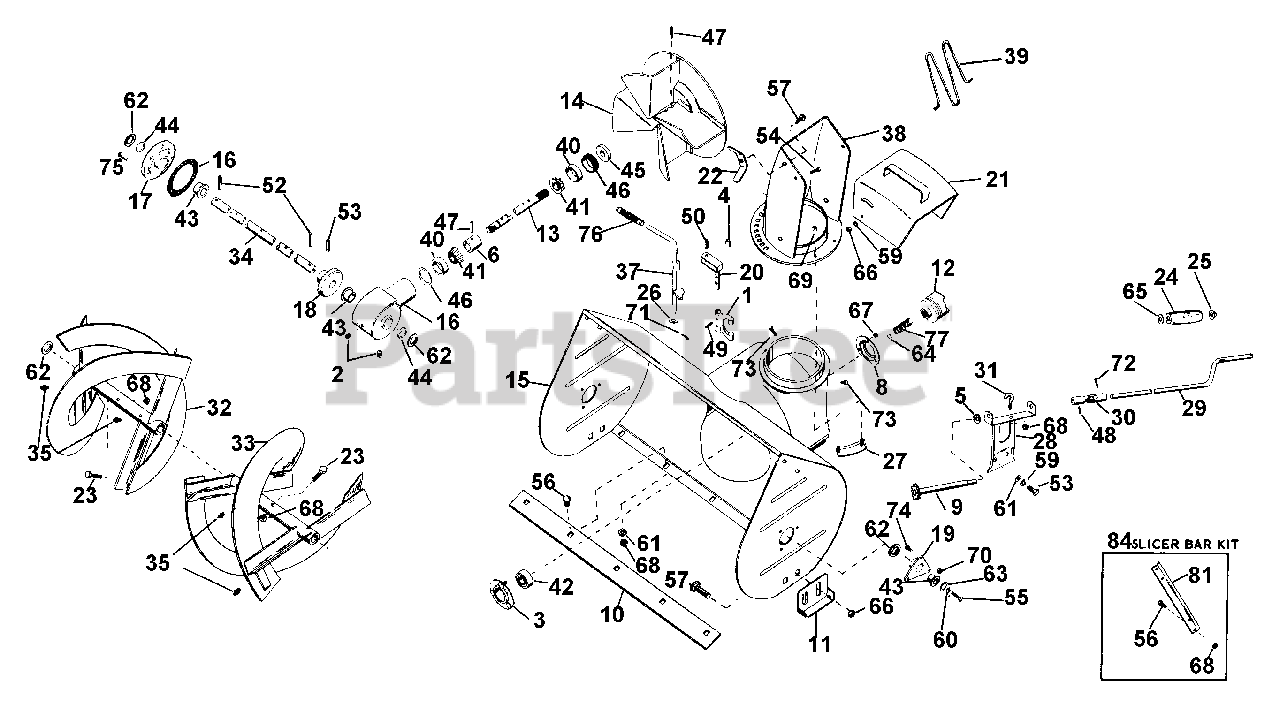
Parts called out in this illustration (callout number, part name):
1	CLUTCH FORK
2	PIPE PLUG
3	BEARING FLANGE
5	WAVE WASHER .531X.781X.125FH
6	BEARING SPACER
8	BEARING FLANGE
9	CONTROL SPROCKET
10	SCRAPER BLADE 24"
11	RUNNER
12	JAW CLUTCH
13	HELICON PINION SHAFT
15	BLOWER HOUSING
16	CASE, GEAR - C.I.
17	GEAR CASE FLANGE
18	HELICON GEAR - 41 TOOTH
19	BEARING SUPPORT
20	FORK SHAFT
21	DEFLECTOR CHUTE
22	WING NUT
23	SHEAR BOLT YWZC
25	CAP, 3/8 ROD YWZC
26	WAVE WASHER .406X.750X.063FH
27	CHUTE CLAMP
28	CHUTE CNTL BRACKET
29	CHUTE CNTL CRANK
30	UNIVERSAL JOINT
32	R H RAKE
33	L H RAKE
34	FRONT GEAR SHAFT
35	HYDRAULIC DRIVE FITTING
36	ADJUSTMENT PLUG
37	FORK CAM
38	DISCHARGE CHUTE
39	SAFETY WIRE
40	BRG-CUP 1.781X.475
41	BRG-CONE .750X.61
42	BRG-BALL .750X1.750X.50
43	BSHG-FLG 1.000X1.12X.62X1.50BR
44	SEAL 1.000X1.312X.150
45	SEAL .750X1.499X.225
46	RG-RTNG INT 1.781 HSG X.062
47	PIN-ROLL .250X1.25
48	PIN-ROLL .125X1.00
49	PIN-ROLL .188X1.00
50	PIN-ROLL .313X1.25
51	PIN-ROLL .313X1.38
52	PIN-ROLL .188X1.50
53	BLT-HEX .31-18X.75 PL GR2
54	BLT-HEX .38-16X.75 PL GR2
55	BLT-HEX .50-13X1.00 PL GR2
56	BLT-RDHDSQSHNK .31-18X.50 YZ
57	BLT-RDHDSQNK .38-16X.75 SHT PL
58	WSHR-LK .312X.097 PL HVY
59	WSHR-LK .375X.115 HVY PL
60	WSHR-LK .500X.151 HVY PL
61	WSHR-FL-STL .38X.875X.083 PL
62	WSHR-FL-STL 1.010X1.505X.062PL
63	WSHR-FL-STL .511X1.441X.125 PL
64	WSHR-FL-STL .755X1.375X.062 PL
65	WSHR-FL-STL .382X.812X.023 PL
66	NUT-LK-CTR .375-16 GR A PL
67	NUT-LK-CTR .250-20 PL
68	NUT-LK .312-18 GR A PL
69	NUT-KEPS 10-24 PL
70	NUT-LK-FLG .250-20 PL
71	PIN-COTR .12X1.0 PL
72	PIN-COTR .12 X 1.25 PL
73	BLT-SCRHFWH .38-16X.50 PL
74	SCR-SLTR-SERNK .25-20X.62 PL
75	BLT-SERHFWH .25-20X.75 PL
77	SG-COMP .105X1.35X1.984
78	SNO-THRO DECAL
79	CAUTION LABEL
80	CLUTCH INSTRUCTION DECAL
81	CUTTER BAR
82	BLT-RDHDSQSHNK .31-18X.50 YZ
83	NUT-LK .312-18 GR A PL
84	SLICER BAR KIT
